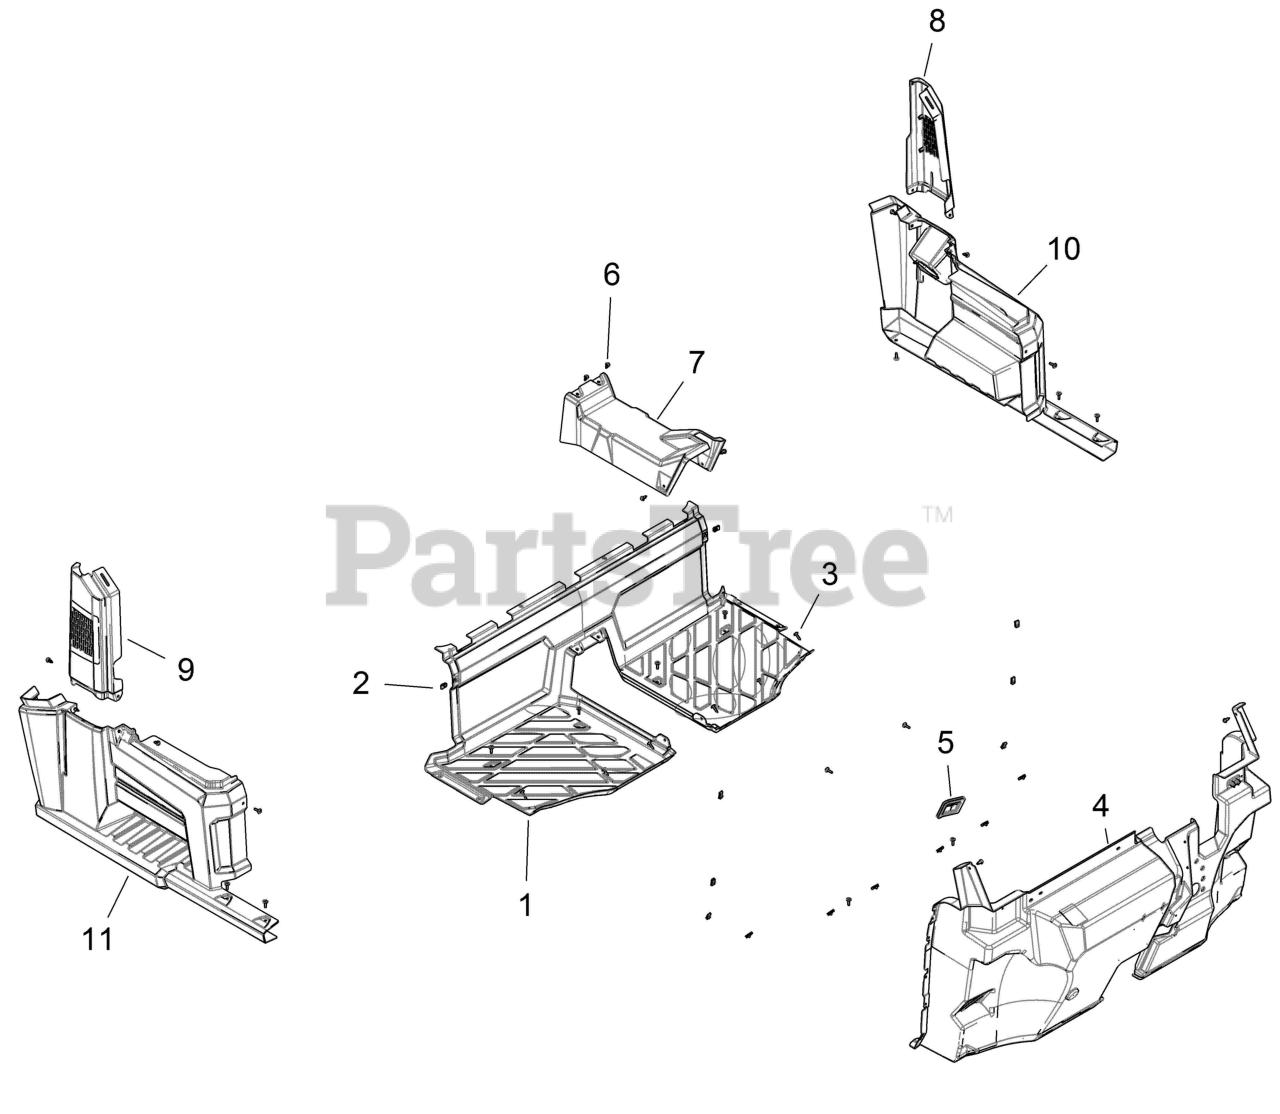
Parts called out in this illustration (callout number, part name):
1	FLOOR-BLK
2	CLIP-U SPEED NUT
3	SCR-TXTH-M6X1.0X25 RIE
4	FLOOR-FRONT,BLK
5	GROMMET-STEERING,FLOOR
6	RIVET-TUFLOK,.315-.325X.787 (5
7	COVER-DRIVE SHAFT,FLOOR,BLK
8	ASM-FENDER-REAR,UPPER,LH,BLK
9	ASM-FENDER-REAR,UPPER,RH,BLK
10	FENDER-REAR,W/ROCKER,LH,ARIENS
11	FENDER-REAR,W/ROCKER,RH,ARIENS
